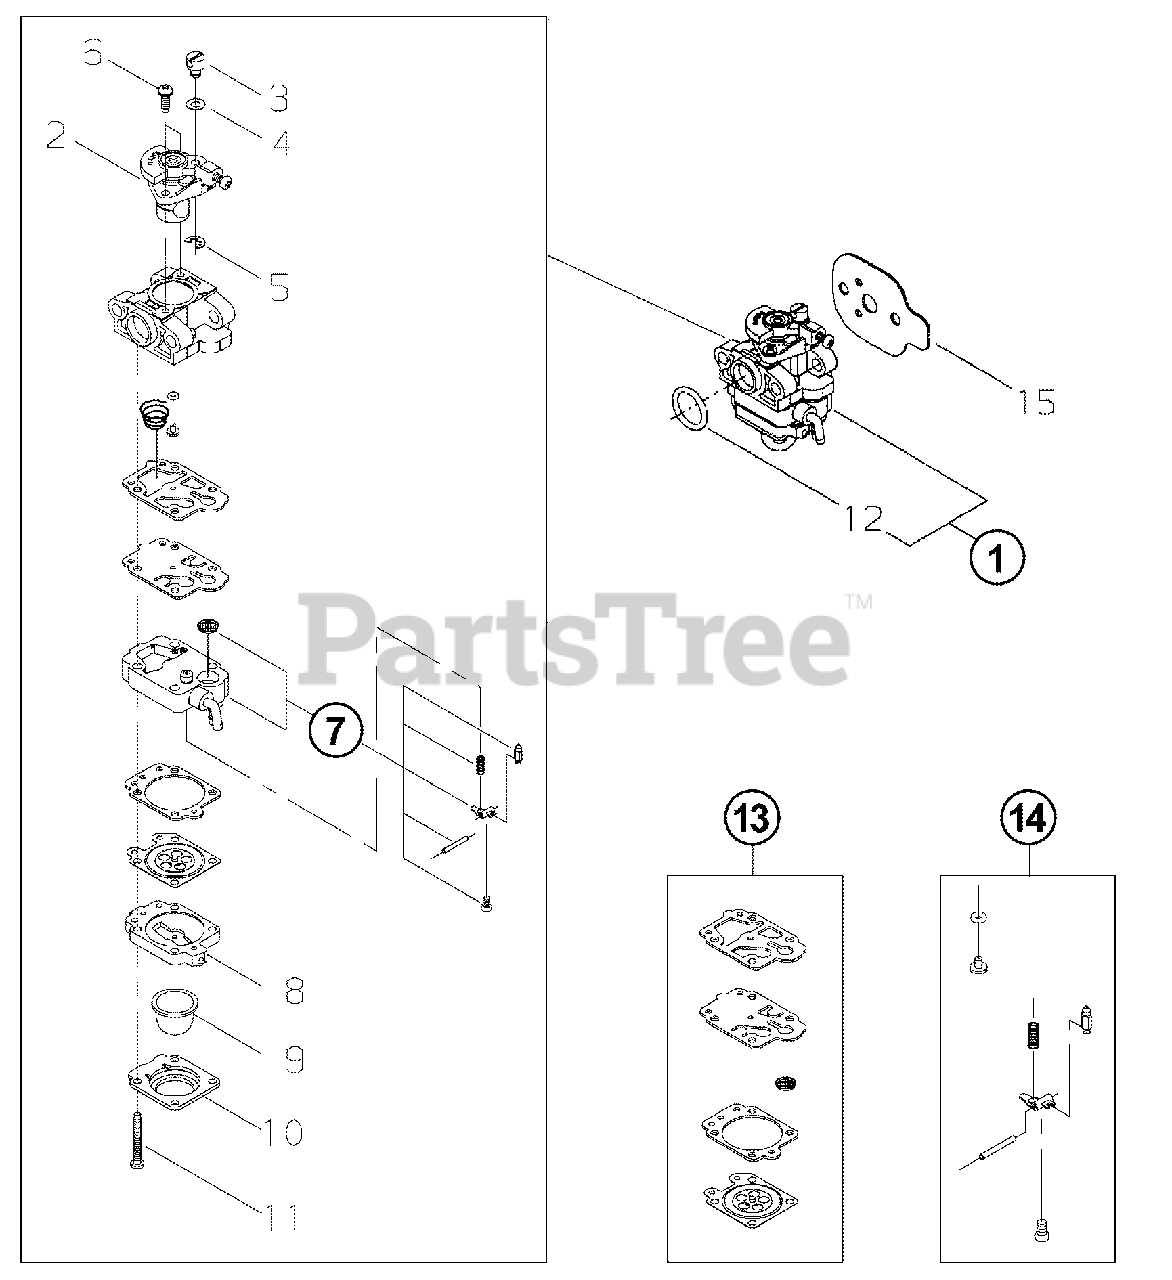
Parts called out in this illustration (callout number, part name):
1	CARBURETOR
2	THROTTLE VALVE ASSY
3	SWIVEL
4	WASHER
5	RING, RETAINING
6	SCREW
7	PUMP BODY ASSY
8	BASE, PURGE
9	BULB, PURGE
10	RETAINER, PURGE BULB
11	SCREW, PUMP COVER
12	O-RING - 15
13	DIAPHRAGM/GASKET KIT
14	INLET NEEDLE VALVE KIT
15	GASKET
